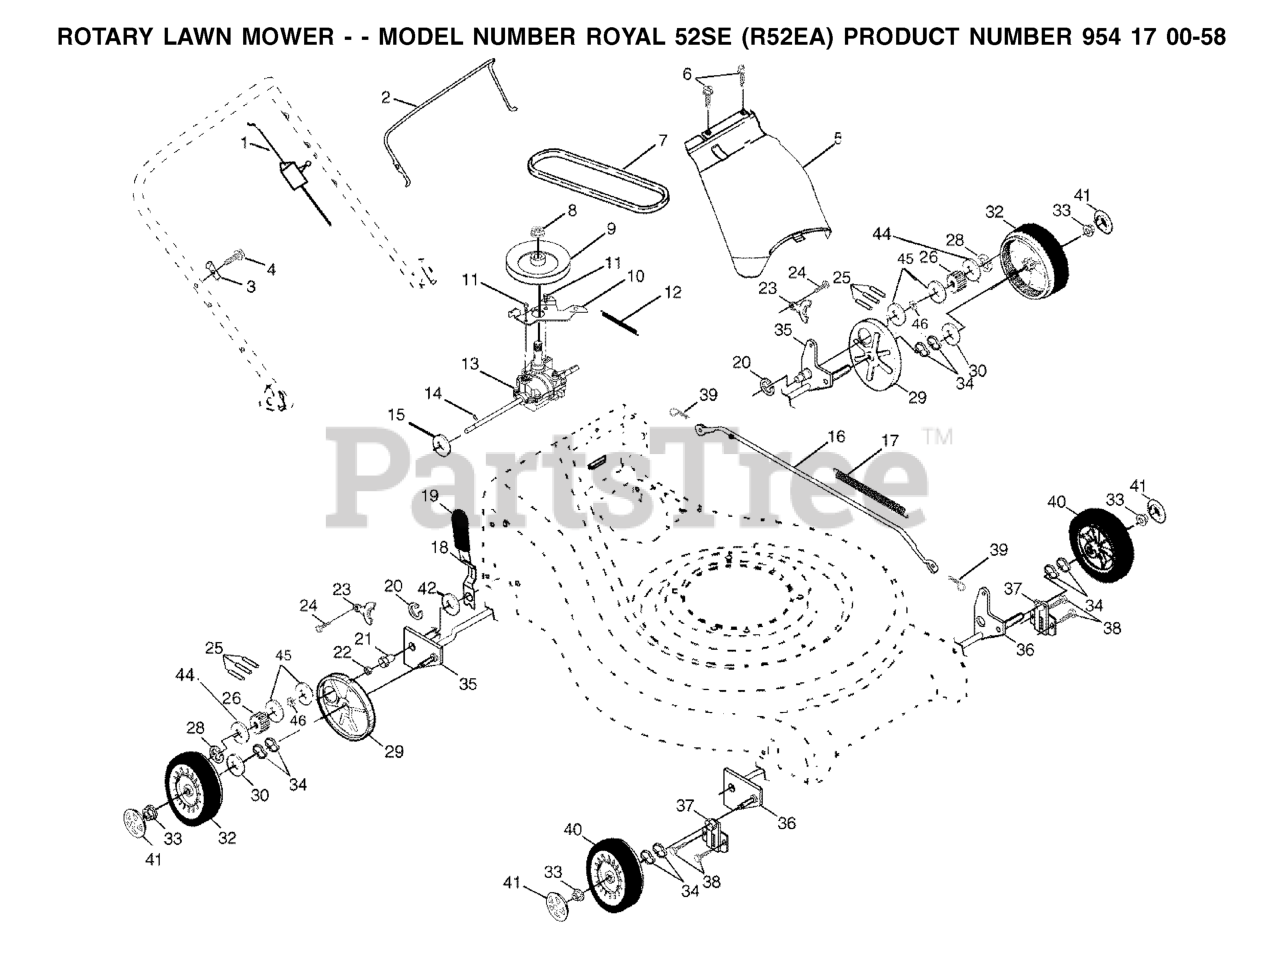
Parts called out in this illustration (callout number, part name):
1	CABLE.DRIVE.21.RWGD.
2	BAIL.CONT.DR.21.RWGD.BLACK
3	DOWNSTOP BRACKET
4	SCREW.HEX.HEAD.WASHER.10-16
8	FLANGED LOCKNUT 3/8-16 ZINC
10	BELT GUIDE
11	Screw, Hex Washer Head #10-24 x .668
13	TRANSMISSION ASM. (WALK)
14	PIN.SPRING.THRUST
15	THRUST WASHER
16	ROD CONNECTING
17	SPRING
18	SPRING
19	KNOB
21	RP BEARING SUPPORT
22	BEARING, BALL
23	BRACKET
25	PAWL.DRIVE.ETCHED
26	PINION.DRIVE.WALK
28	E-RING 7/16 RE
29	DUST COVER, WHEEL
30	WASHER FLUT
32	WHEEL.9X2.PR.LP.RADIAL.BK.BB.3
33	HEX FLANGE LOCKNT
34	WAVE WASHER
35	SHAFT ASSY
36	SHAFT ASSY
37	RETAINER.FRONT.SHAFT
39	RETAINER CLIP
40	WHEEL ASMBLY FRONT
41	CAP.HUB.ARC.SPOKE.8".LP
42	WASHER.ZINC.PLATED
45	WASHER.BELLEVILLE (3 2 LB)
